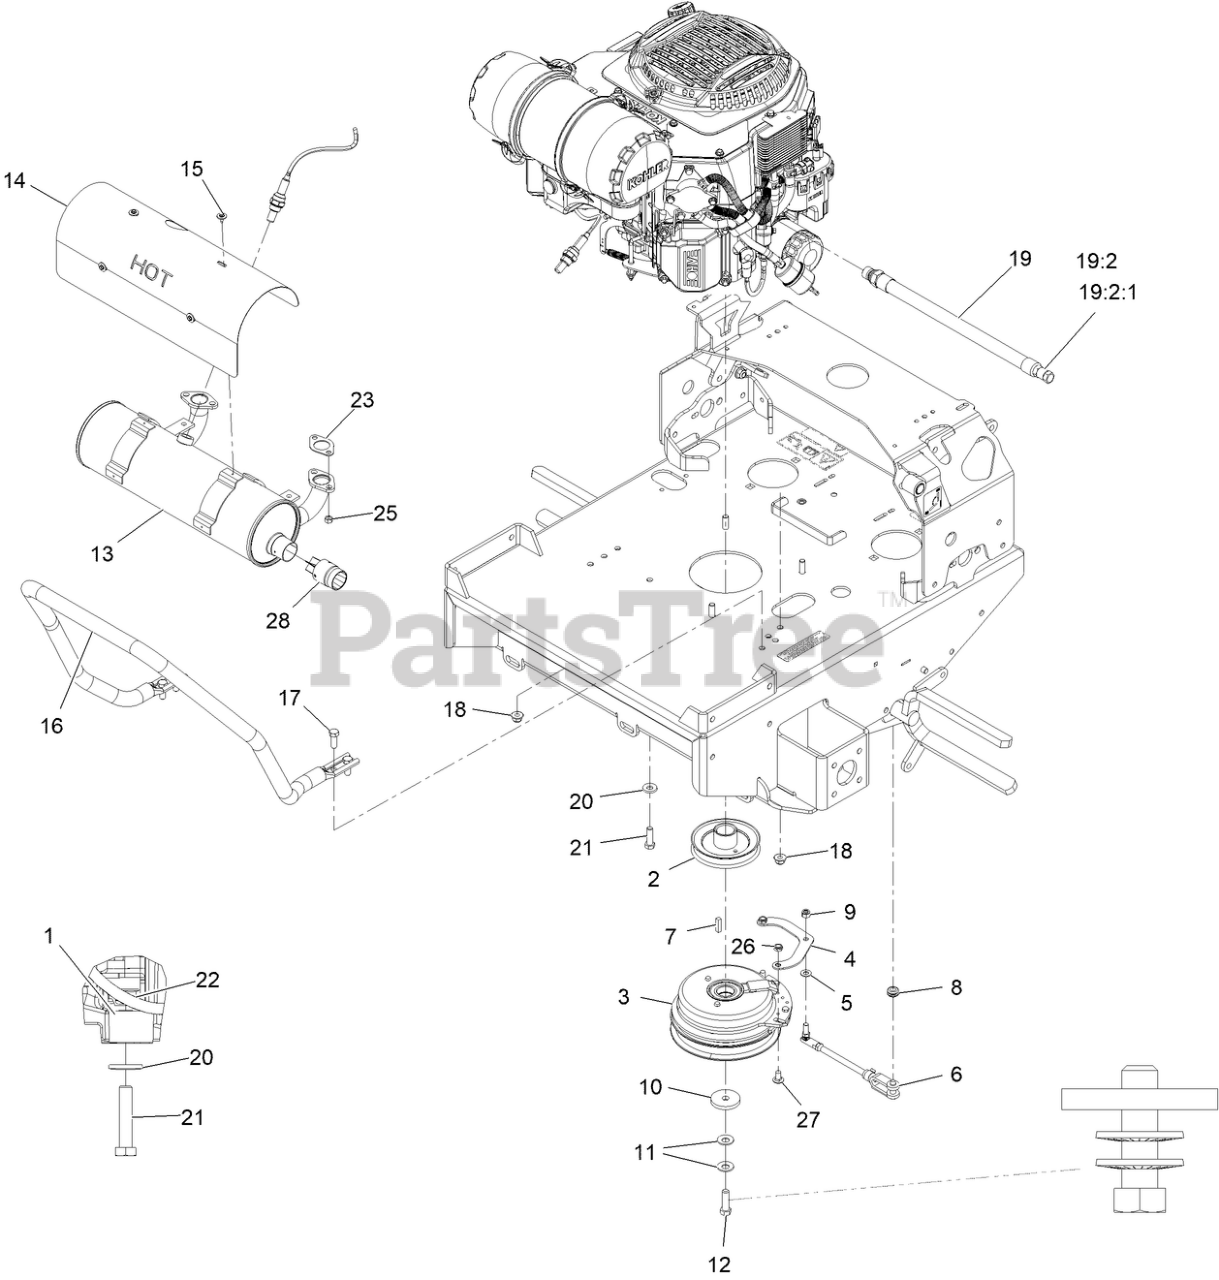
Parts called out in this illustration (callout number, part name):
2	SHEAVE W/ HUB
3	CLUTCH, 200 FT/LBS, 1.13
4	STRAP, CLUTCH
5	WASHER-PLAIN
6	ASM, CLUTCH ANCHOR
7	KEY
8	GROMMET
9	NUT-LOCK
10	WASHER-CLUTCH
11	WASHER-SPRING
12	BOLT-HEX, TAP
13	MUFFLER-TTX, EFI
14	SHIELD-MUFFLER,TTX EFI
15	SCREW-HH, THREAD FORMING
16	TUBE-GUARD AIR CLEANER
17	SCREW-HH
18	NUT-HF, NI
19	OIL DRAIN HOSE ASM
19:2	PLUG-HH
19:2:1	O-RING
20	WASHER-SPRING
21	SCREW-HH
22	NUT-HF, NI
23	GASKET-EXHAUST
25	NUT-FLANGE
26	NUT-LOCK, NI
27	SCREW-CARR
28	Screen-Spark Arrestor
